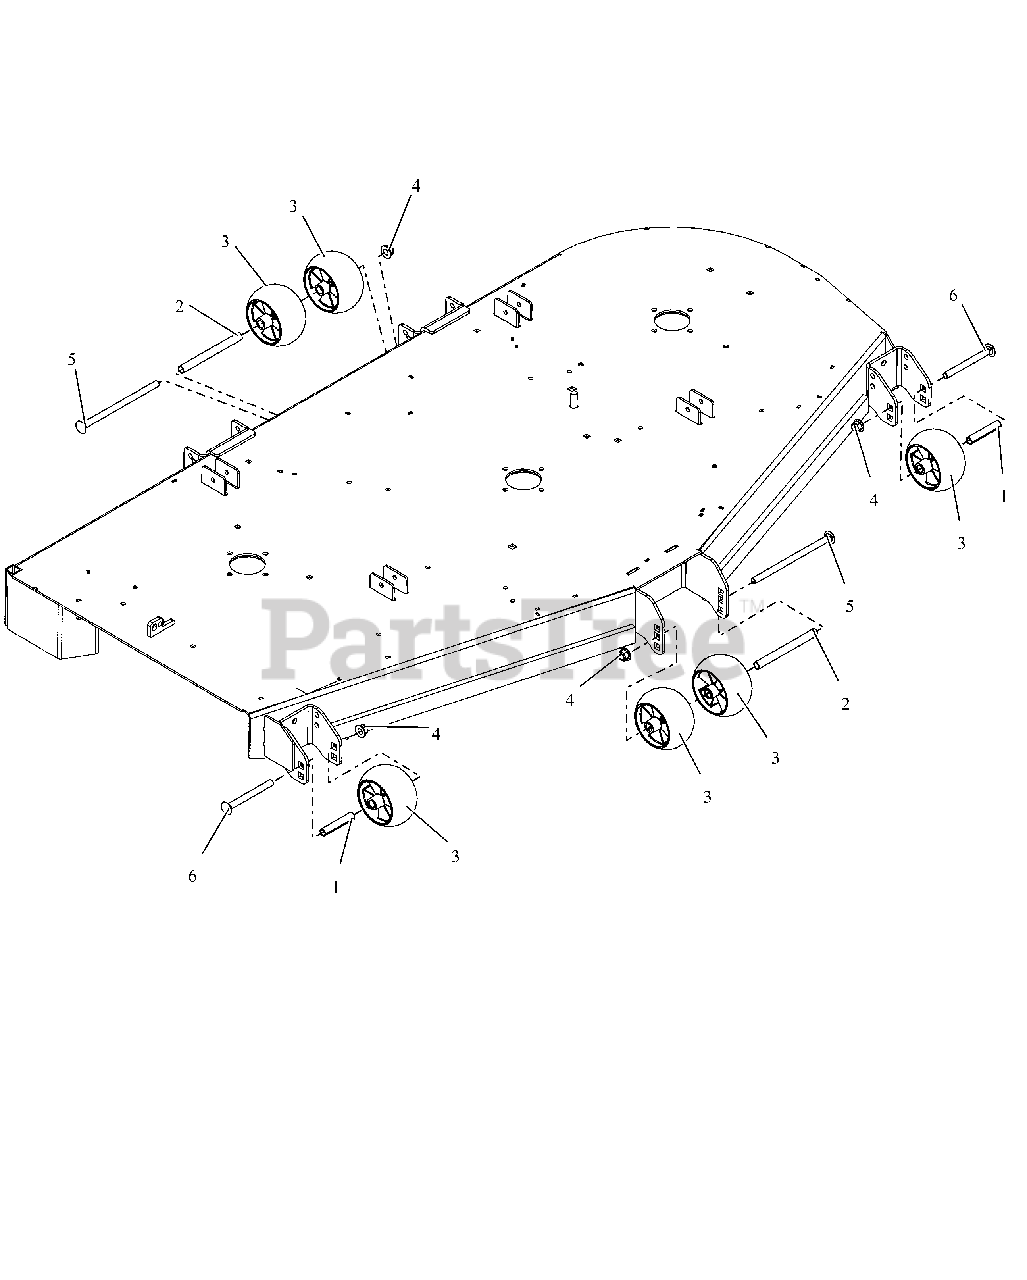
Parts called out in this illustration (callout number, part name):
1	SPACER, .510X.625X3.35
2	SPACER, .510X.625X6.50
3	ANTI-SCALP WHEEL - 5X3 CTR
4	NUT,NYL-FLG .50-13 GF ZCC
5	BLT, RHSN .50-13X8.50 G5 ZCC
6	BLT, RHSN .50-13X5.00 G5 ZCC
